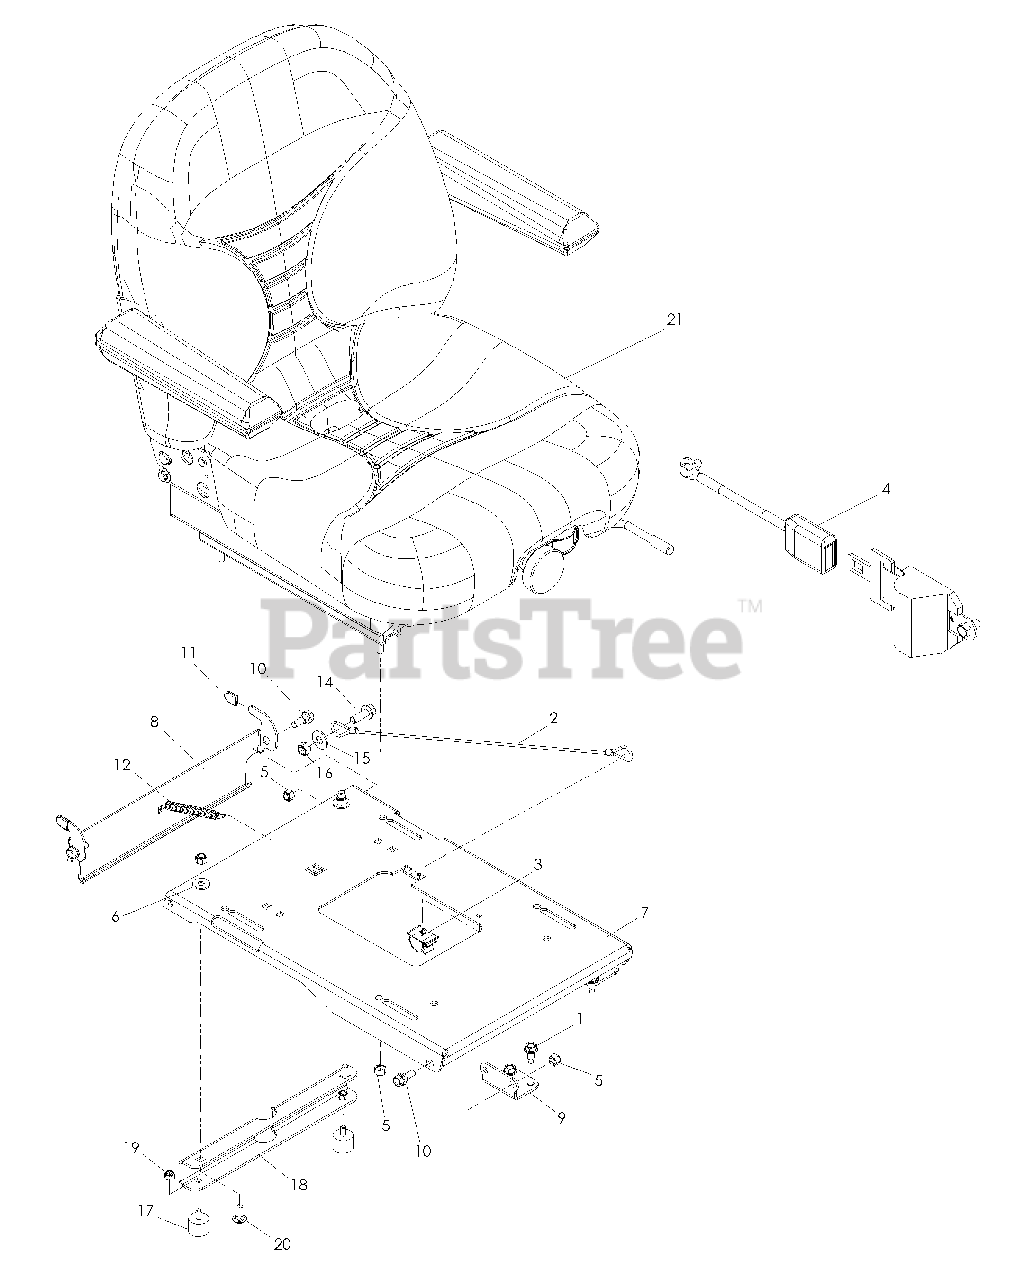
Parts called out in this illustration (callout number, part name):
1	BOLT 5/16-18 x 3/4 THRD FRM
2	LANYARD, SEAT
3	CLIP, WIRE
4	SEAT BELT, RETRACTABLE
5	NUT 5/16-18 HEX NYLOC
6	WASHER 5/16 STD FLT
8	LATCH, SEAT
9	PIVOT, SEAT PAN
10	BOLT 5/16-18 HEX HD
11	GRIP, VINYL
13	HCS 5/16-18 x 1
14	HCS 3/8-16 x 1 WHIZLK
15	WASHER 3/8 FLAT STD
16	NUT 3/8-16 HEX NYLOC
17	STUD PLATE MOUNT
18	STANDOFF, SEAT PAN
19	NUT 1/4-20 HEX NYLOC
20	RHSNB 5/16-18 x 3/4
